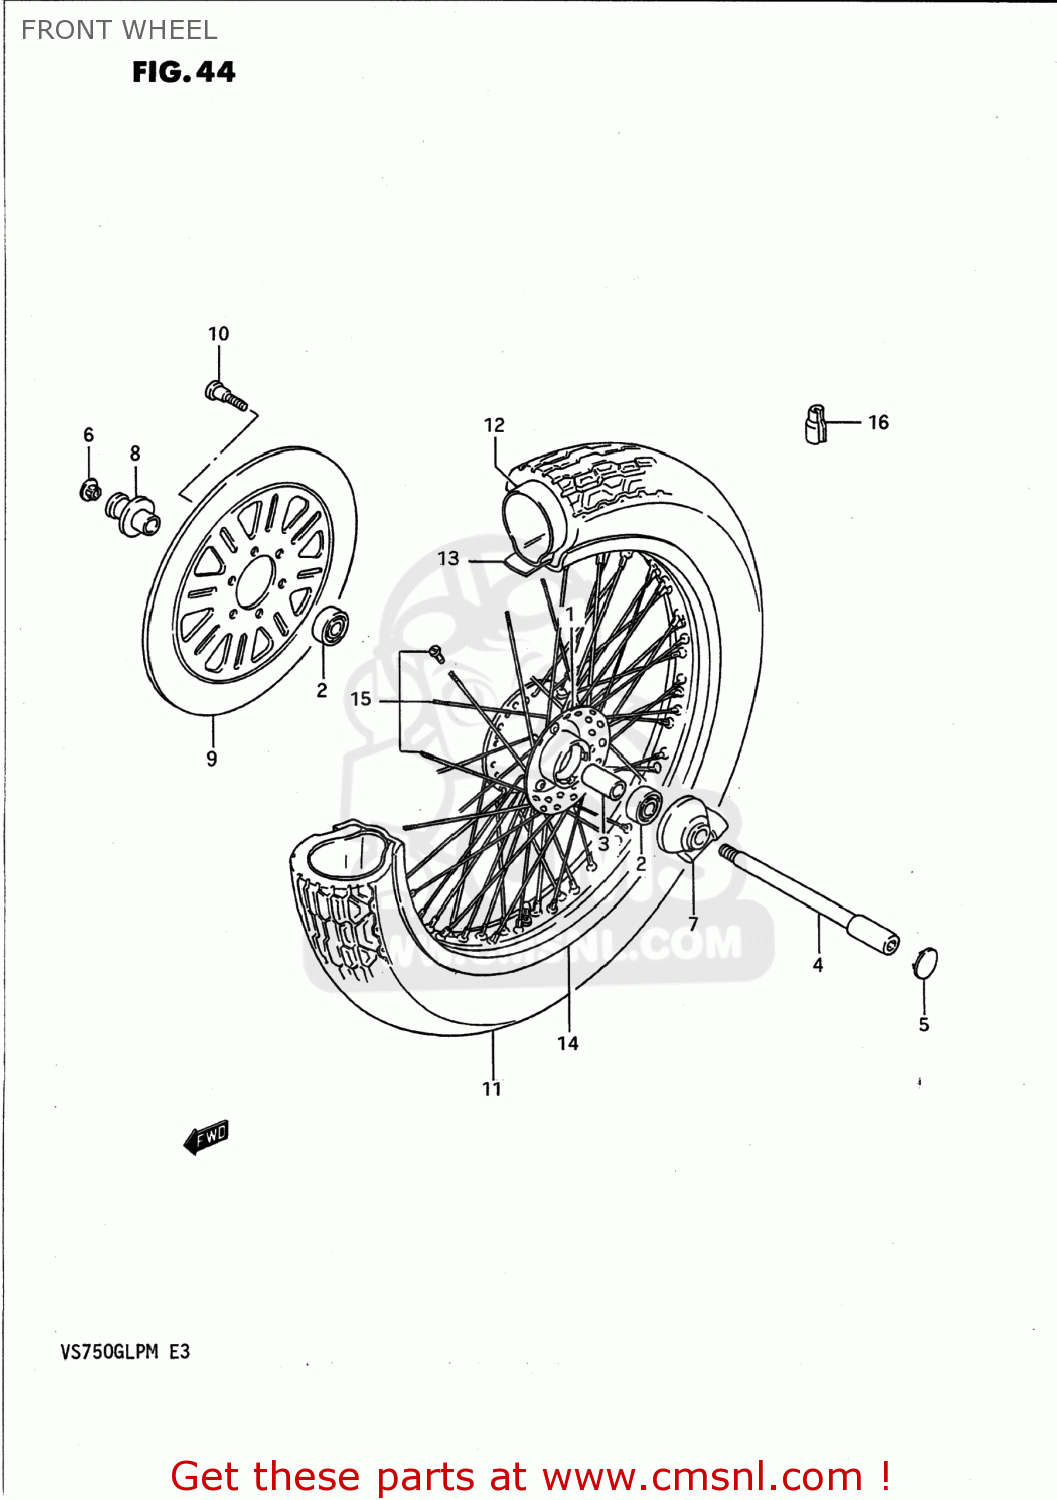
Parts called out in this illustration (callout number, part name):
1	HUB ASSY,FR
2	BEARING
3	SPACER(15.3X21.7X65)
4	AXLE,FR
5	CAP,FR AXLE
6	CAP,FR AXLE
7	BOX ASSY,SPEEDOMETER
8	SPACER,FR AXLE
9	DISC,FR BRAKE
10	BOLT(8X25.5)
11	TIRE,FR(80/90 21 48H)
12	TUBE,INNER
13	PROTECTOR,WHEEL,INNER
14	RIM,FR WHEEL(21X2.15 AL)
15	SPOKE SET,FR WHEEL
16	BALANCER,WHEEL
